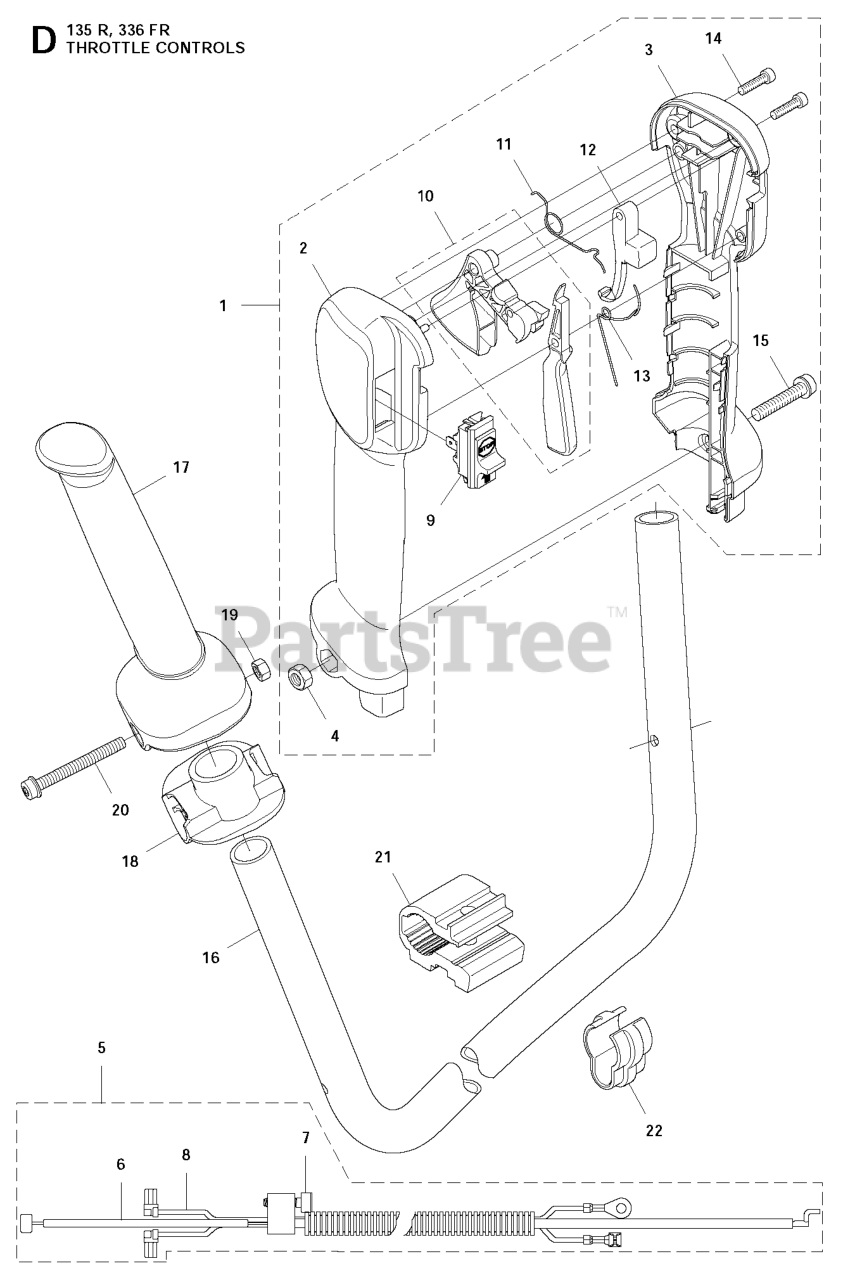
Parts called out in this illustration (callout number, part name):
1	HANDLE ASSY 336FR
2	HANDLE
2	HANDLE HALF LEFT
3	HANDLE
5	WIRING KIT COMPLETE
6	THROTTLE WIRE
8	SHORT CIRCUIT CABLE
9	STOP BUTTON
10	THROTTLE CONTROL
12	LOCKOUT STARTER THROTTLE
15	SCREW
21	CLAMP
